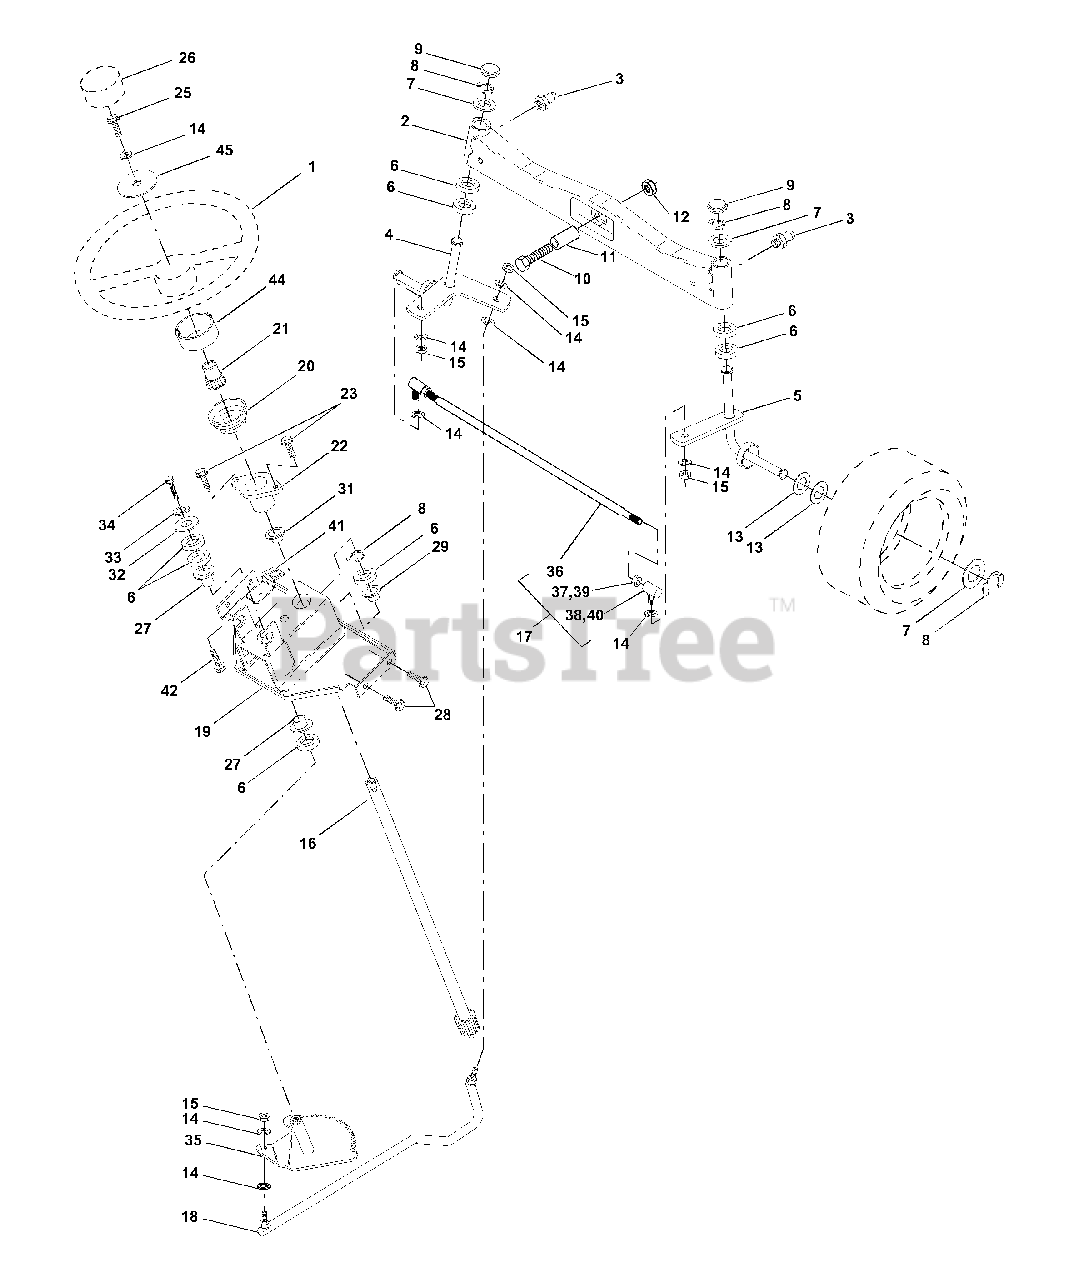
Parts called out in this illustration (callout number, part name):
1	Wheel, Steering
2	Axle Asm., Front
3	Fitting, Grease
4	Spindle Asm, LH
5	Spindle Asm., RH
6	Bearing, Race Thrust Harden
7	Washer 25/32 x 1-5/8 x 16 Ga.
8	Ring, Klip #T5304-75
9	Cap, Spindle
10	Bolt, Fin Hex 5/8-11 x 2-3/4
11	Spacer, Brg. Axle Front
12	Nut, Lock Flange 5/8-11 Unc
13	Washer 25/32 x 1-1/4 x 16 Ga.
14	Washer, Lock Hvy Hlcl Spr 3/8
15	Nut Lock Center 3/8-24 Unf
16	Shaft Asm., Steering
17	Rod Tie Service
18	Draglink, Ball Joint Solid Vgt
19	Support Asm., Steering Vgt
20	Boot Steering Stealth
21	Adapter, Wheel Steering
22	Bushing, Strg.
23	Screw
25	Bolt, Fin Hex 3/8-16 x 1 Gr. 5
26	Insert Cap Strg WH
27	Bearing, Col. Strg.
28	Screw Hexwsh thdr 3/8-16 x 3/4
29	Bearing, Flange
31	Bushing, Nyliner Snap
32	Washer 11/32 x 1 x 10 Ga.
33	Washer, Lock Hvy Hlcl Spr 5/16
34	Bolt, Hex Hd 5/16-18 x 3/4
35	Gear, Sector Steering
36	Tie Rod
37	Jam Nut RH Thread
38	Joint Asm. Ball RH Thread
39	Nut Hex Jam 3/8-24
40	Joint Asm. Ball LH Thread
41	Bracket Switch Interlock Vgt 97
42	Screw Thdrol 5/16-18 x 1/2 Tyt
44	Extension Steering
45	Washer 13/32 x 1-1/2 x 11 Ga.
